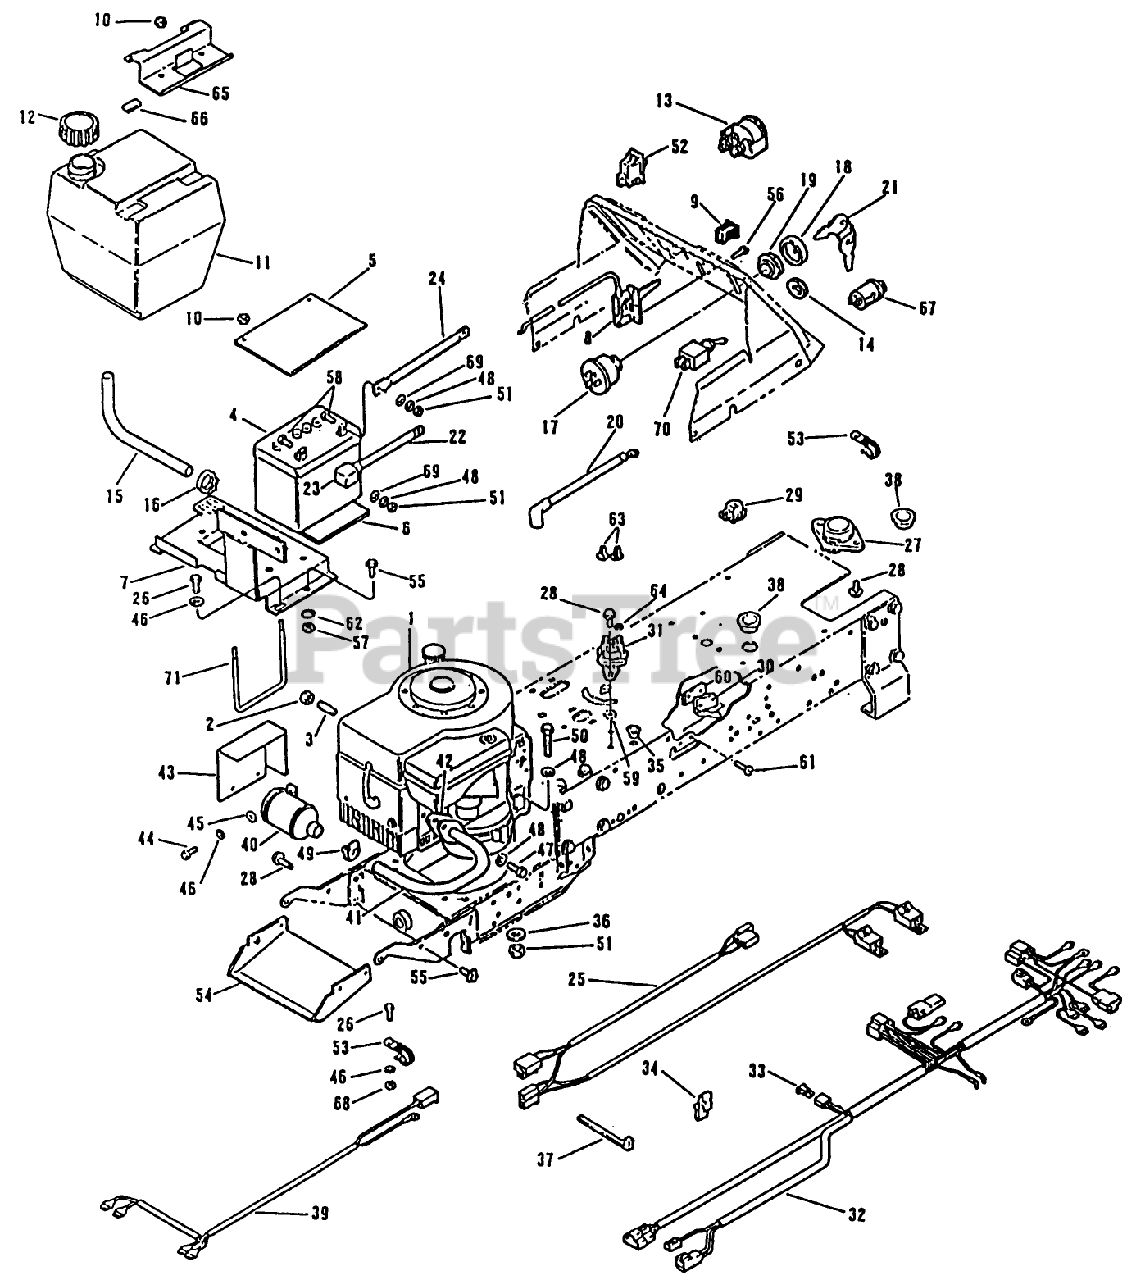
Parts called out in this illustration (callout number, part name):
9	THROTTLE KNOB
10	NUT-LOCK, CONE
11	FUEL TANK ASSEMBLY
12	CAP AY - FUEL M
18	BEZEL
19	NUT
21	KEY
22	CABLE ASSEMBLY
27	SWITCH,SEAT
29	SWITCH
30	SWITCH
31	SOLENOID
40	MUFFLER AY
42	GASKET
44	SCREW
51	NUT SS
52	SWITCH ASSEMBLY
58	SCREW - HEX
64	NUT-HEX
67	LIGHT-PTO INDICTOR
68	NUT
70	SWITCH-PTO W/SAFTY
